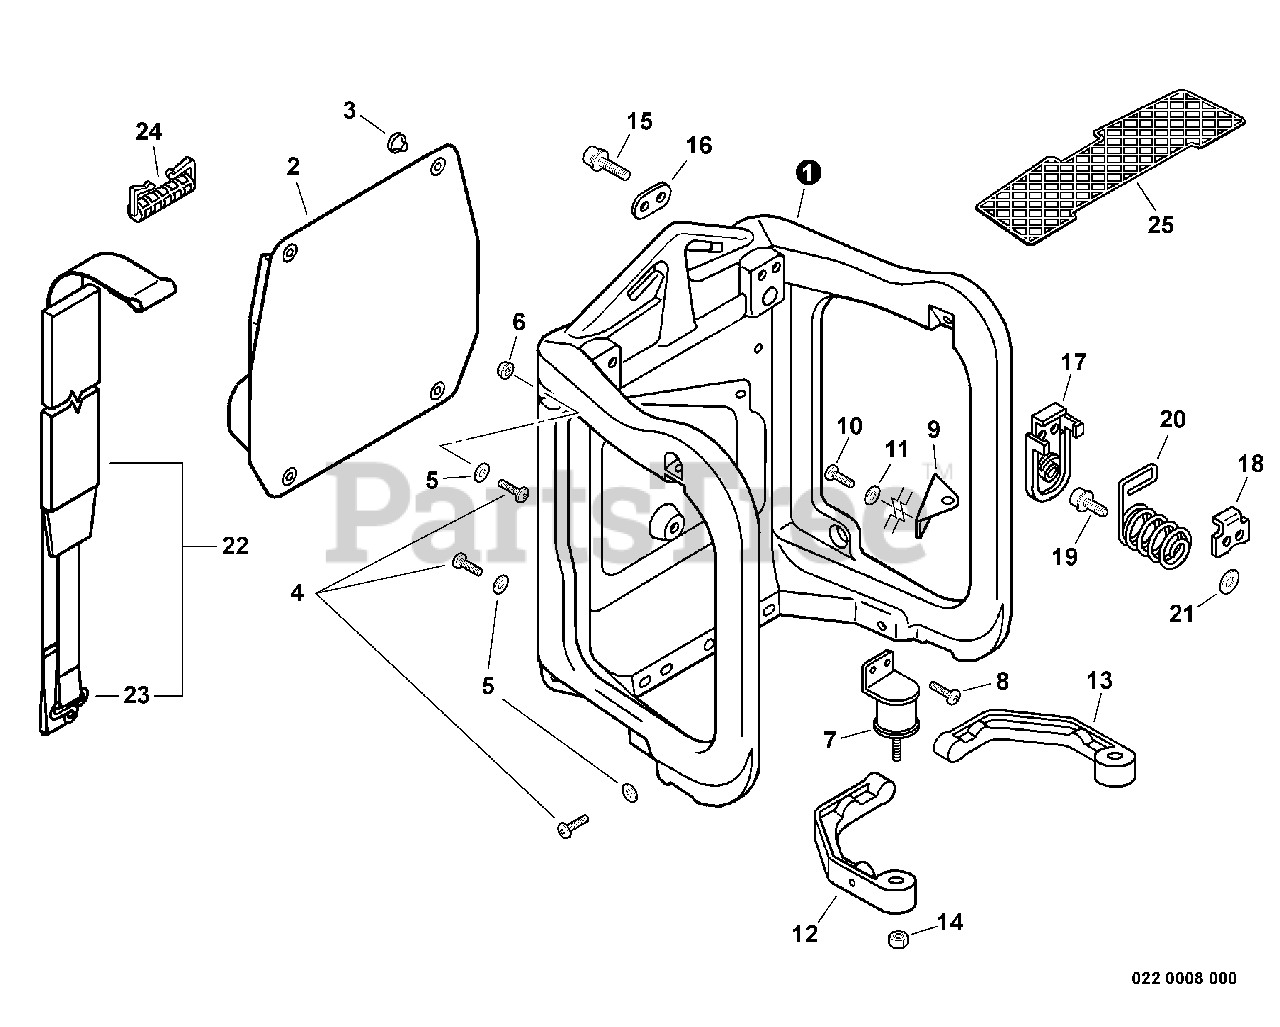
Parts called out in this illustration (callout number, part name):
1	FRAME, BACKPACK
2	CUSHION, BACKPACK
4	SCREW - 5X16 -- TAPPING
6	NUT - 5 -- FLANGE
7	CUSHION
8	SCREW - 5X16 -- TAPPING
9	BRACKET, HANGER
10	SCREW - 5X20
12	CONNECTOR, FRAME - LEFT
13	CONNECTOR, FRAME - RIGHT
14	NUT - 5 -- FLANGE
15	SCREW - 5X16 -- TAPPING
17	BRACKET, SPRING
18	RETAINER
19	SCREW - 5X20
21	WASHER - 5
22	BACKPACK STRAP ASSY
24	RETAINER, HARNESS
25	COVER, DUST
